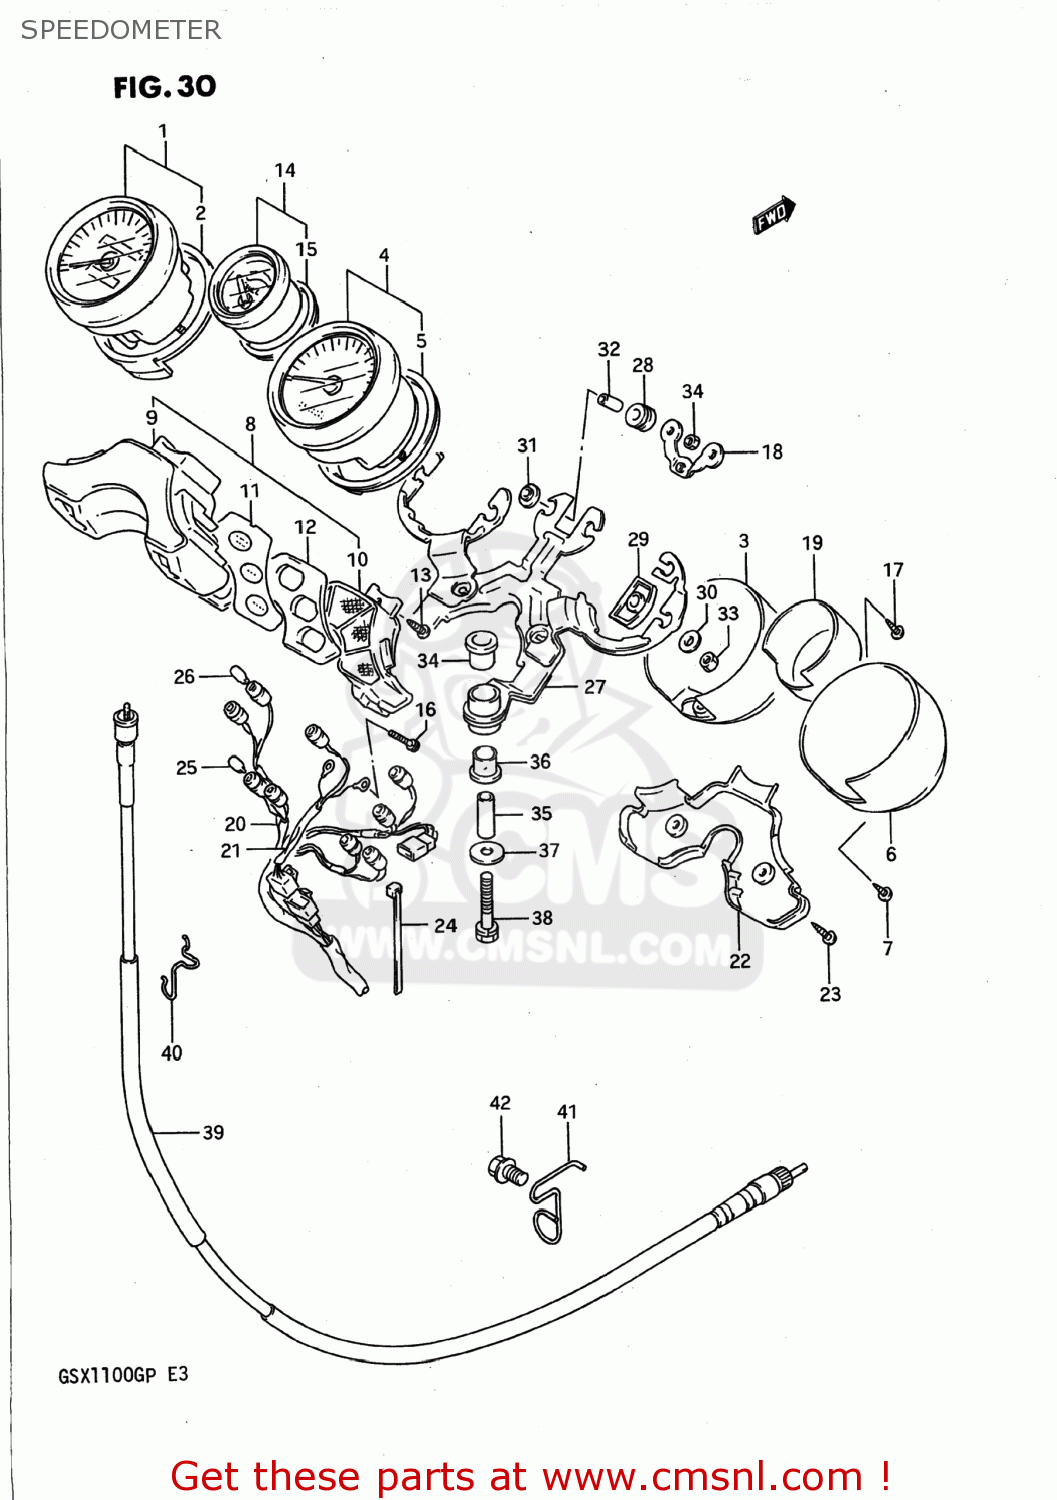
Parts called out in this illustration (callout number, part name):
1	SPEEDOMETER
2	DAMPER
3	COVER,SPEEDOMETER
4	TACHOMETER
5	DAMPER
6	TACHOMETER
7	SCREW,METER
8	BOX,PILOT
9	CASE,UPR
10	LWR CASE
11	PANEL
12	GASKET (NAS)
13	SCREW
14	FUEL METER
15	DAMPER
16	SCREW(3X22)
17	SCREW
18	PLATE,SET
19	COVER,FUEL METER
20	SOCKET,METER
21	SOCKET,FUEL METER
22	COVER,PILOT BOX
23	SCREW
24	CLAMP
25	BULB(12V3W,T6.5)
26	BULB(12V1.7W,T6.5)
27	BRACKET,METER
28	DAMPER
29	CUSHION,METER
30	WASHER
31	WASHER,FUEL,METER
32	SPACER,FUEL METER
33	NUT 5MM
34	NUT
35	BUSHING L:34
36	CUSHION
37	WASHER (8.2X26X1.6)
38	BOLT
39	CABLE ASSY,SPEEDOMETER
40	GUIDE,SPEEDOMETER CABLE
41	CLAMP,SPEEDOMETER CABLE
42	BOLT
